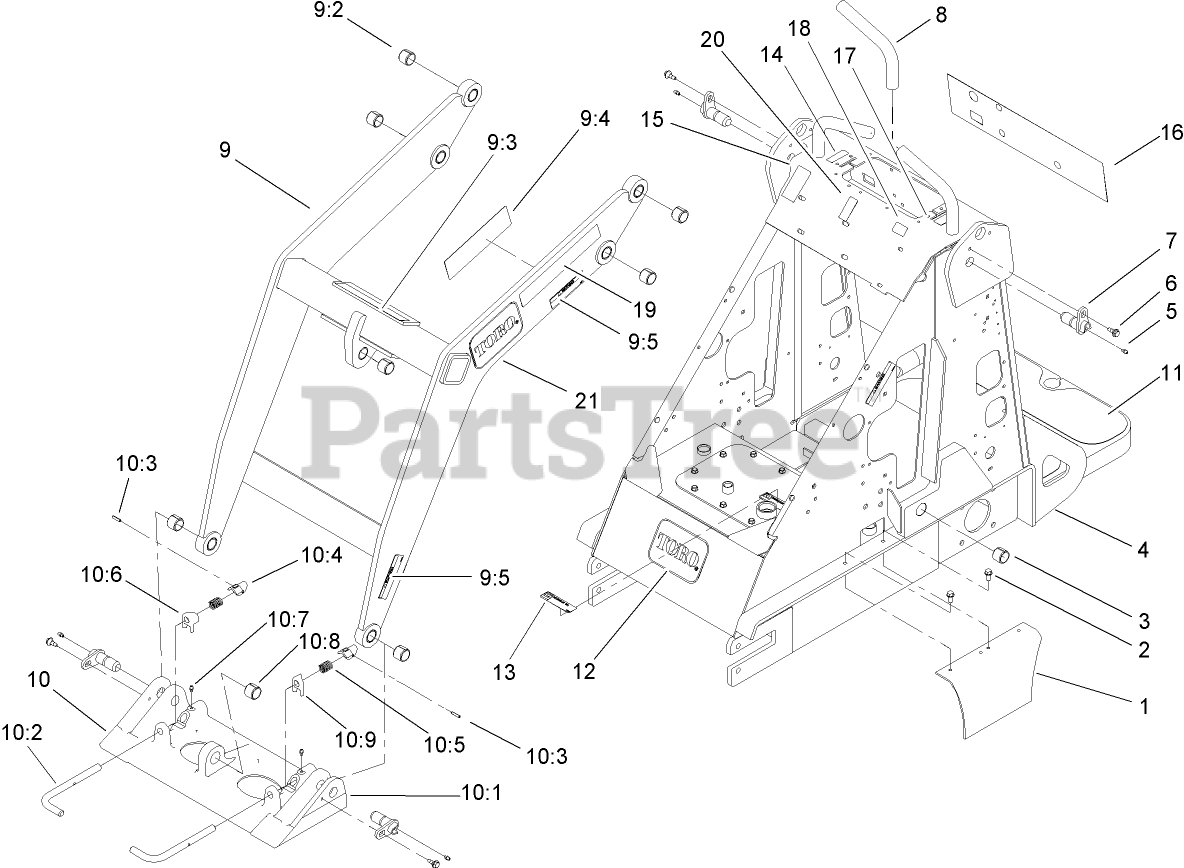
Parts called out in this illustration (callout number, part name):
1	COVER-CHAIN
2	SCREW-HWHTF
3	BUSHING-TENSION
4	FRAME ASM
5	FITTING-GREASE
6	BOLT-SHOULDER
7	PIN-PIVOT
8	GRIP-CUSHION
9	LOADER ASM
9:2	BUSHING-TENSION
9:3	DECAL-CAUTION
9:4	DECAL-DANGER
9:5	DECAL-PINCH
10	QUICK ATTACH ASM
10:1	MOUNT-ATTACH, QUICK
10:2	PIN-LOCKING
10:3	PIN-GROOVED
10:5	SPRING-COMPRESSION
10:6	STOP-RH
10:7	FITTING-GREASE
10:8	BUSHING-TENSION
10:9	STOP-LH
11	TREAD-FOOT
12	DECAL
13	DECAL-OIL, HYD
14	DECAL-CHOKE
15	DECAL-POWER, AUXILIARY
16	DECAL-PANEL, CONTROL
17	DECAL-THROTTLE
18	DECAL-LIMITER, SPEED
20	DECAL-SELECTOR
21	DECAL
